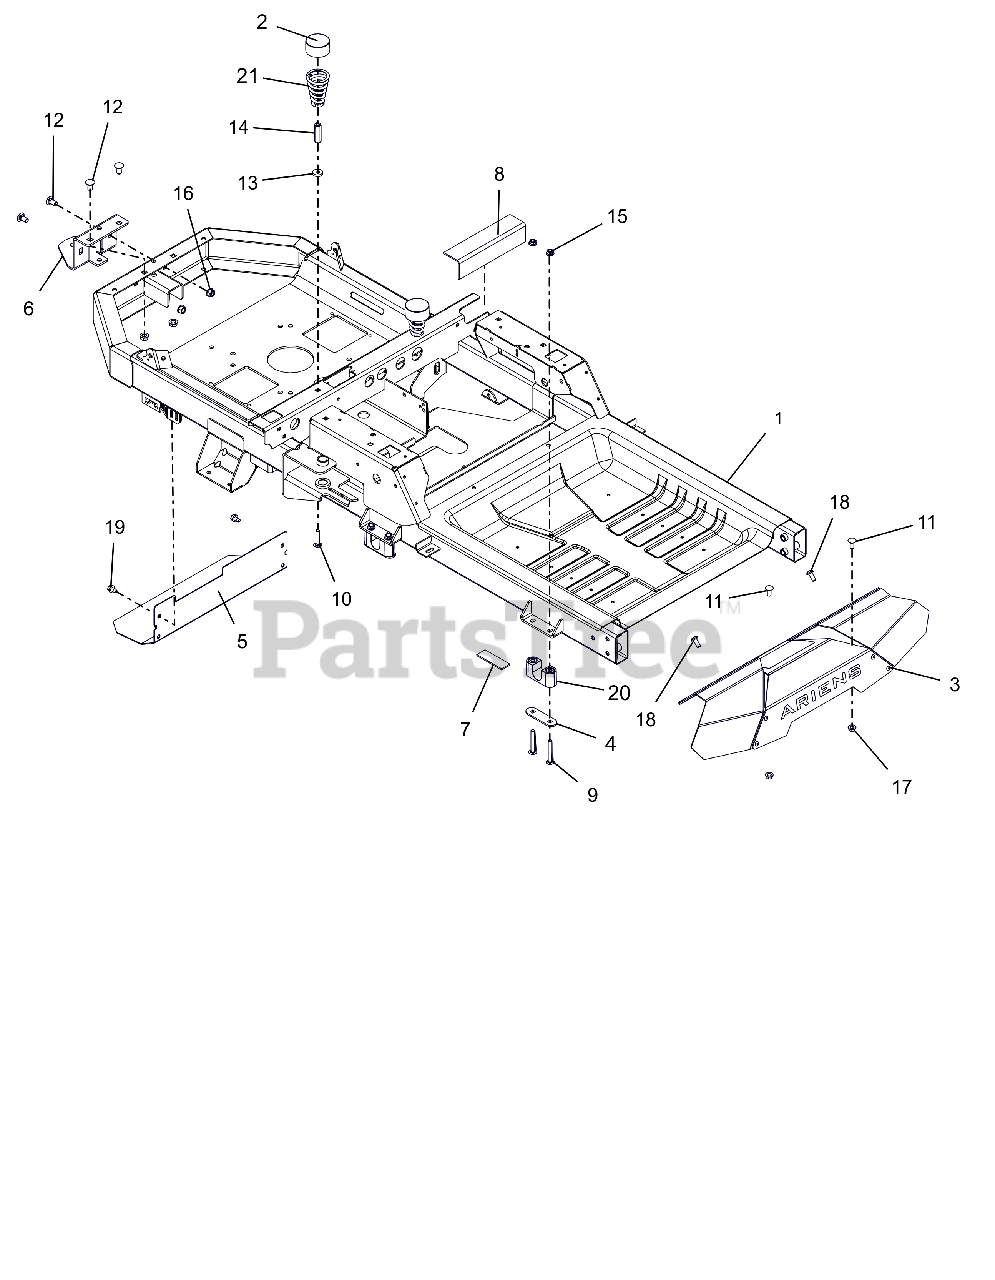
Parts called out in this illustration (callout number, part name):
1	KIT, IKON-X/XL FRAME (2016)
2	HUB CAP
3	KIT, IKON FOOT REST W/DECAL
4	PLATE, BEARING SUPPORT
5	HEAT, SHIELD
6	BRKT, HITCH TONGUE
7	PAD,RBR 1.0"X3.0" W/ADHESIVE
8	PAD, RUBBER-TANK
9	BLT-RDHDSQSHNK .31-18X2.25 YWZ
10	@BLT-RDHDSQNK .31-18X1.50 G5YZ
11	@BLT-RDHDSQNK .31-18X.75 G5YZ
12	@BLT-RDHDSQNK .38-16X.75 G5YZ
13	WSHR-FL-STL .328X.87X.179 YWZC
14	NUT, COUPLING 5/16-18 X 1 3/4
15	@NUT-LK-CTR-FLG .31-18 YZ GR F
16	@NUT-LK-TOP-FLG .38-16 YWZC
17	@NUT-LK-TOP-FLG .31-18 YWZC
18	SCR-RDHDSKTAP .31-18 X .75
19	@SCR-TAP .31-18X.50 HWH TR YWZ
20	BSHG, DECK LIFT PIVOT
21	SPRING, SEAT
